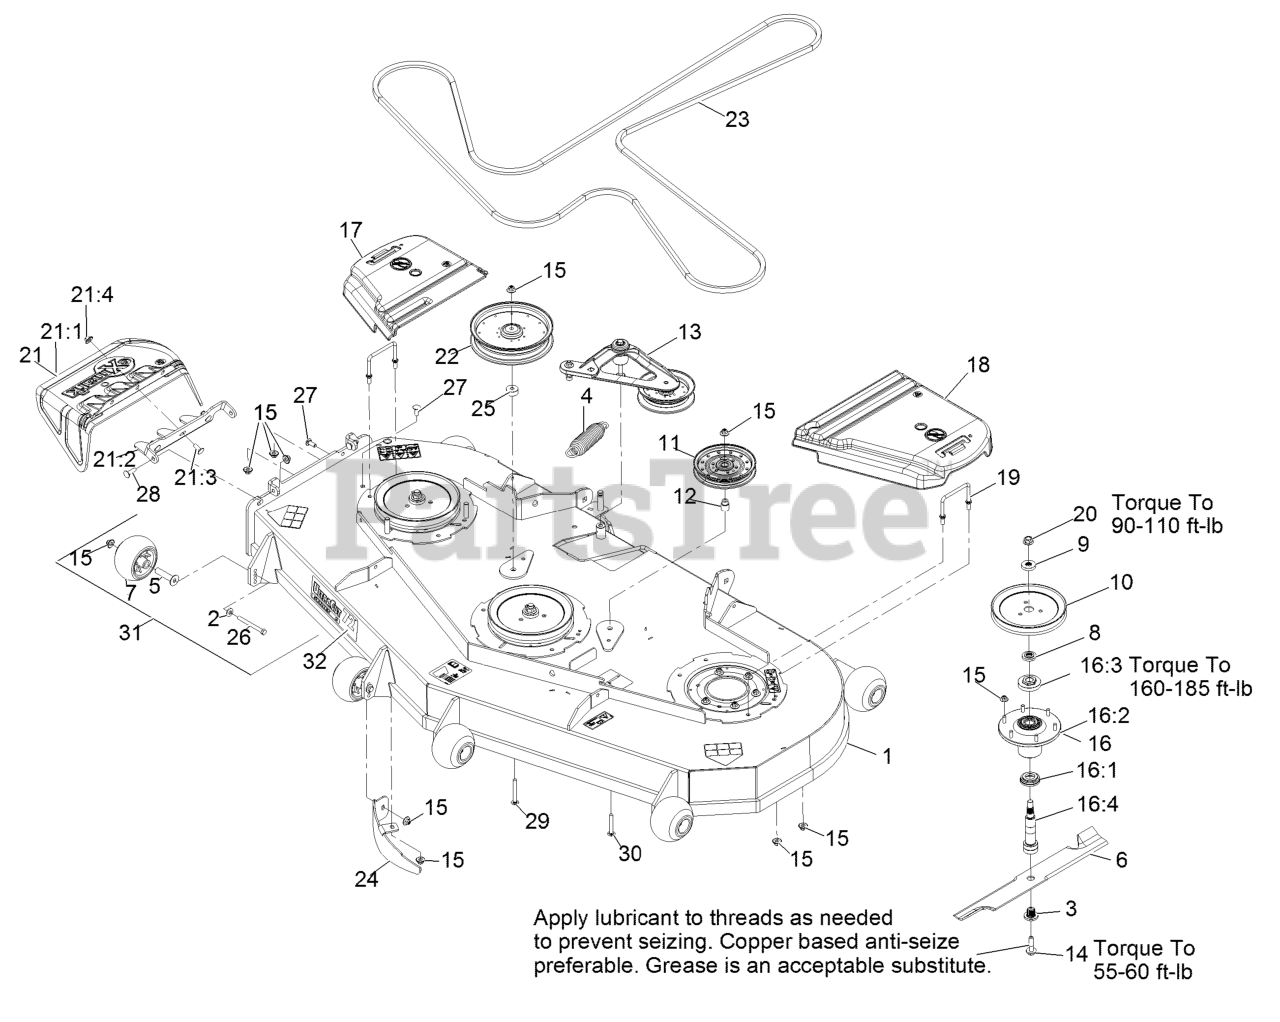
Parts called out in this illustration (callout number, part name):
1	DECK W/ DECALS ASM-72
2	WASHER-BELLEVILLE
3	BUSHING,SPLINED
4	SPRING-EXTENSION
5	AXLE, ROLLER
7	ROLLER-SCALP, ANTI
8	SPACER,SPLINED STEPPED
9	SPACER,SPLINED
10	SHEAVE,BLADE DRIVE 9.00
12	BUSHING-IDLER
13	DECK IDLER ASM
14	SCREW,SEMS 1/2-20 X 2.19
15	Nut-Nyloc 3/8-16 Flg
16	ASM,SPINDLE HOUSING
16:1	GUARD,BOTTOM
16:2	ASM,CUTTER HOUSING
16:3	NUT, SPINDLE 7/8-14
16:4	SPINDLE,DOUBLE SPLINE
17	COVER-BELT, RH
18	COVER-BELT, LH
19	WIREFORM-COVER
20	NUT-FLANGE, CENTERLOCK
21	ASM,DISCHARGE CHUTE
21:1	CHUTE,DISCHARGE
21:2	BRACKET,DISCHARGE CHUTE
21:3	SCREW-CARR
21:4	Nut-Nyloc 3/8-16 Flg
22	PULLEY-IDLER
23	BELT-V
24	BAFFLE-DOGLEG, LZ72
25	SPACER-IDLER
26	SCREW-HH 3/8-16 X 3 3/4 GR 8
27	SCREW-CARR
28	Bolt-Carriage 3/8-16 X 1 1/4
29	SCREW-CARR
30	SCREW-CARR
31	KIT, ANTI-SCALP ROLLER
32	DECAL,ULTRACUT 72 SERIES
